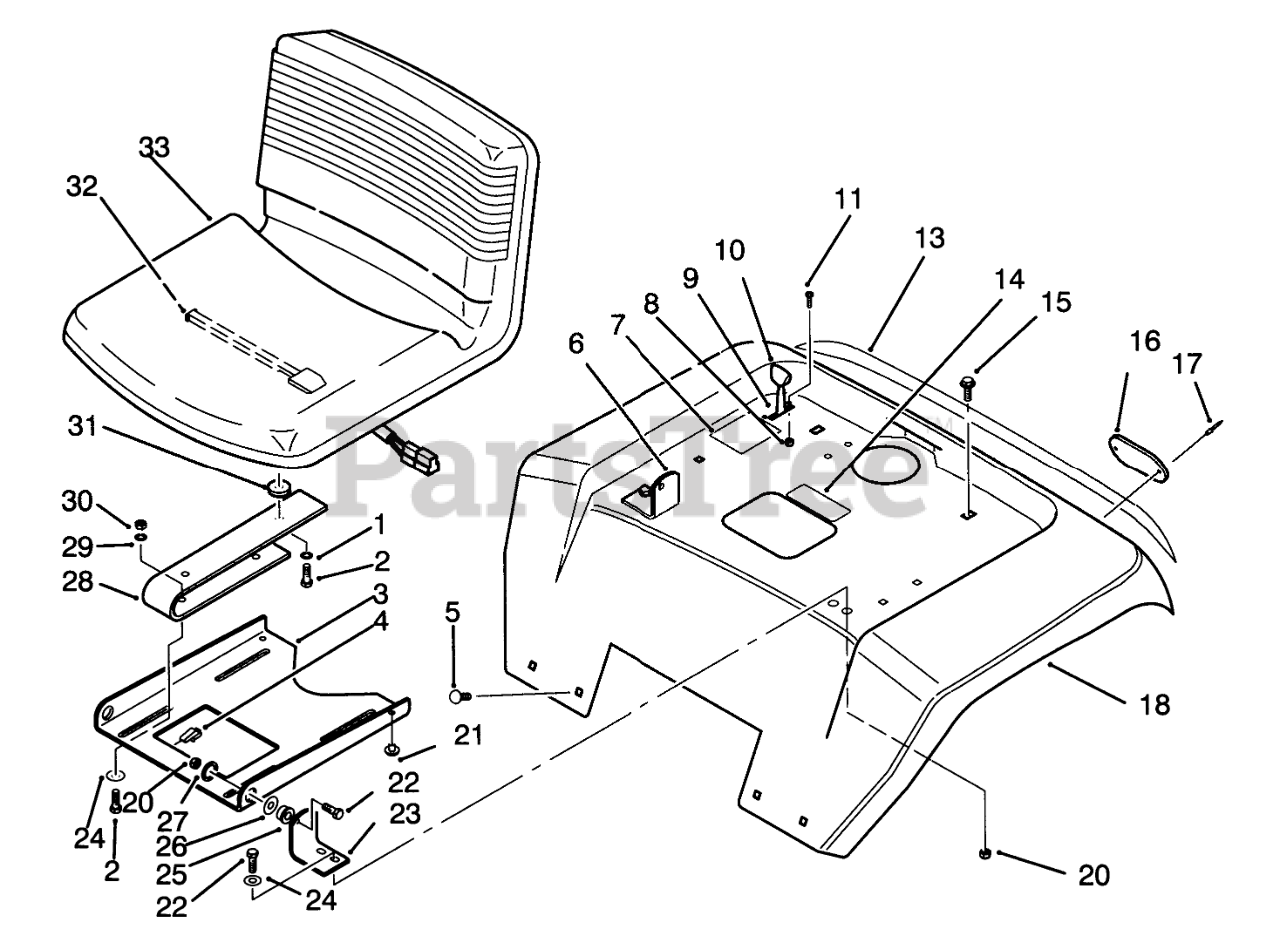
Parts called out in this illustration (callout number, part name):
1	WASHER-LOCK
2	SCREW-HH
3	Plate-SeatPivot
4	J-CLIP
5	SCREW-CARR
6	Bracket-Pivot RH
7	DECAL-PUSH
8	Nut
9	CONTROL-PUSH VALVE
10	KNOB-THROTTLE
11	SCREW
13	DECAL-FENDER
14	DECAL - DANGER
15	Screw
16	Reflector
17	Poprivet
18	Fender (Incl. Ref. #14)
20	NUT-LOCK, NI
21	BUMPER SJ5514 BLACK
22	SCREW-HH
23	BRKT-PIVOT L.H. B
24	WASHER-PLAIN
25	BUSHING
26	WASHER-SPECIAL
27	WASHER-SPRING
28	Seat Spring
29	WASHER-LOCK
30	NUT-HEX
31	SPACER-NYLON
32	SWITCH-SEAT
33	SEAT V-410
